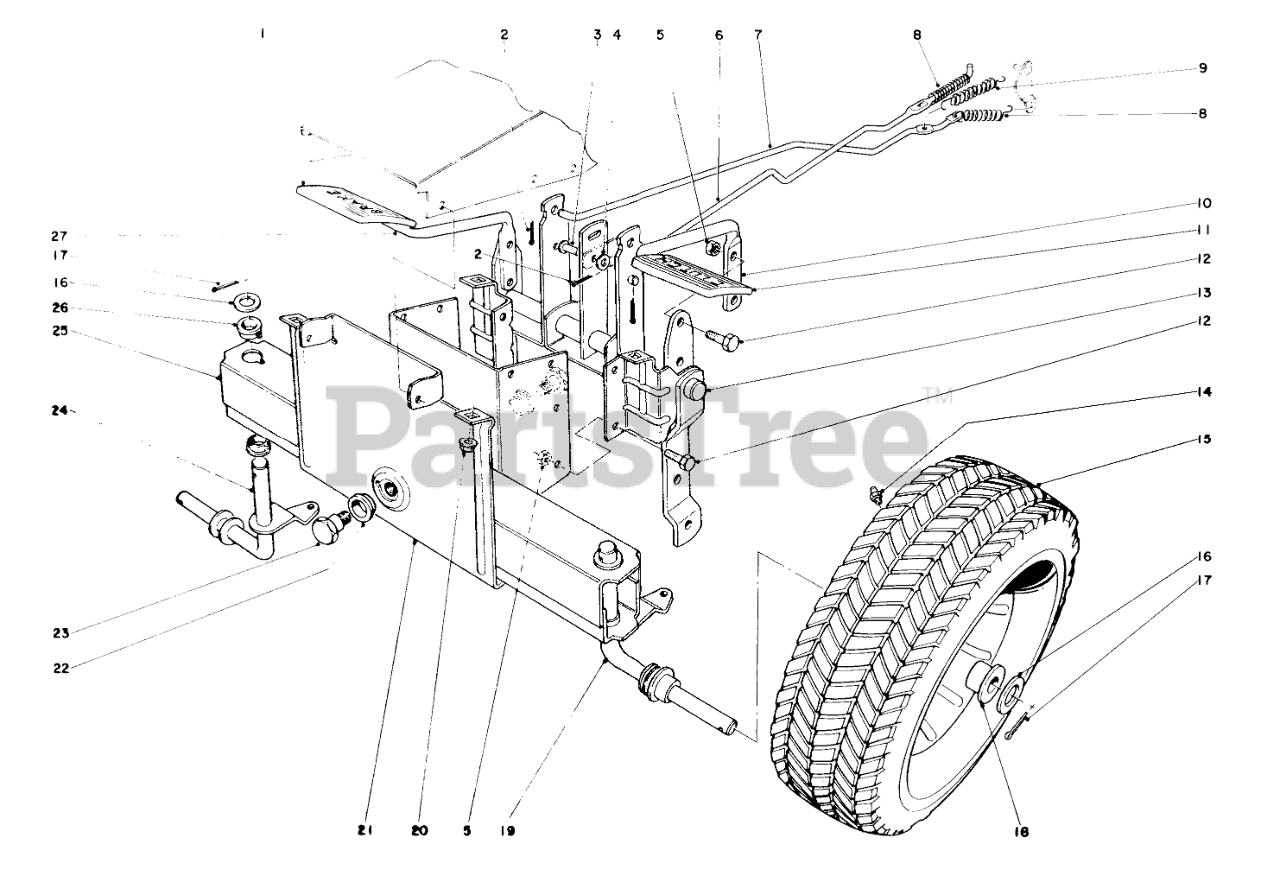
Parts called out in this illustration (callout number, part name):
1	PAD-BRAKE
2	PIN-COTTER
3	PIN-CLEVIS
4	WASHER-PLAIN
5	Nut
6	Clutch Rod
7	Brake Rod
8	Spring
9	Spring, Brake
10	Clutch Pedal
11	CLUTCH PAD
12	SCREW-HH
13	Control Shaft W.A.
14	FITTING-GREASE
15	Wheel
16	WASHER-FLAT
17	PIN-COTTER
18	BUSHING
19	Spindle L. H.
20	NUT-HF
21	Frame Lower Front
22	Bushing
24	Spindle R. H.
25	Front Axle
26	Bushing
27	Brake Pedal
